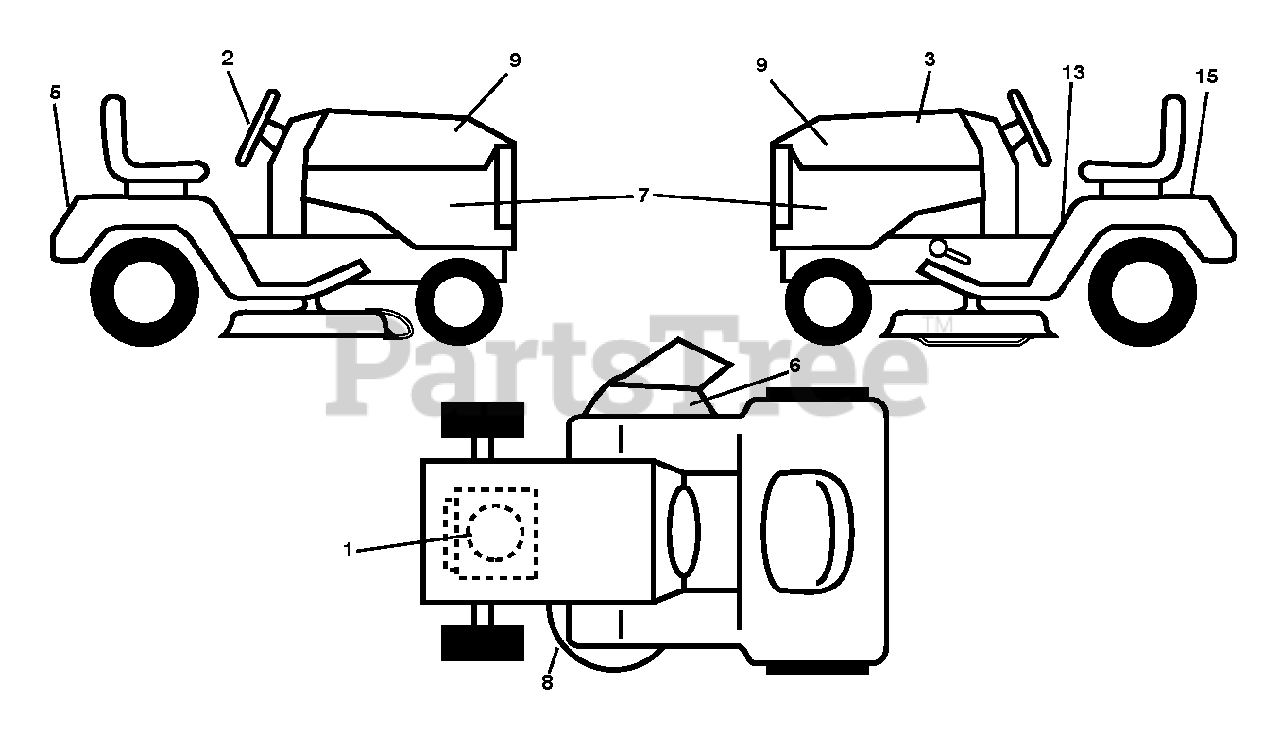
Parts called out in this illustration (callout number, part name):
1	DECAL.ENG.BS.15_5HP.DOM.381681
3	DECAL.RPL.BSM31.PB.STL.42.PMST
6	DECAL.MOWER.WARN.KEEP.HAND.AWY
8	DECAL.V-BELT.SCH.42/46"MEC/ELE
13	DECAL.WARNING.2007.ENG/FR
15	DECAL BTRY SYMBOLS
